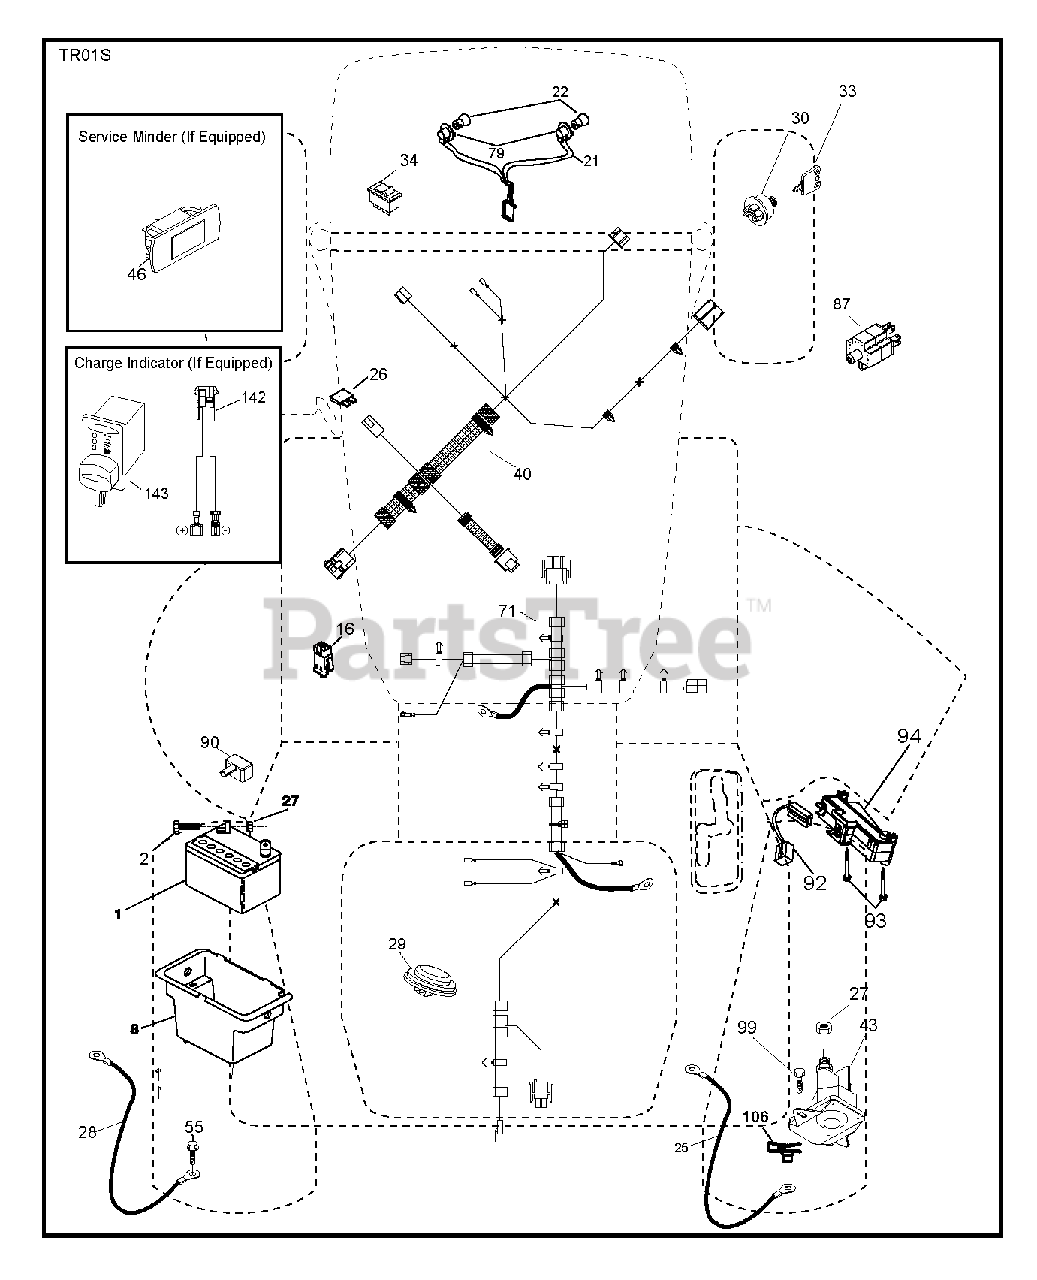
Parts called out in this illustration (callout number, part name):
1	Battery, Dry 30 Amp
2	BOLT.HEX.1/4.X.3/4.DICHROMATE
8	BOX.BATTERY.MNT.REAR.L
16	SWITCH INTERLOOK PUSH-IN
21	HARNESS.LIGHT W/4152J BULBS
25	CABLE.BATT.RED.8GA.17
26	FUSE 20AMP
27	NUT
28	CABLE.GROUND.REAR.BATTERY.8G
29	SWITCH.SEAT.DELTA.OPC.
30	SWITCH.IGN.DELTA.W.LGH.ROS
33	KEY.CHAIN.BLISTER.PACK.GEN.INT
40	HARNESS.TEX.DASH.MAN.REAR BATT
43	SOLENOID.STARTER.BRASS.PLUNGER
55	SCREW 5/16"
71	HARNESS.CHASSIS.RRBATT.RDYSTRT
79	BULB HOLDER ASM.
87	SWITCH.INTRLCK.CLUTCH.
90	COVER.TERMINAL.BATTERY
92	HARNESS.PIGTAIL.CONSLE
93	SCREW.PLASTITE
94	MODULE.REVERSE.ROS
99	SCREW HEXWSHR 1/4-20X3/4
106	1/4-20 U NUT
